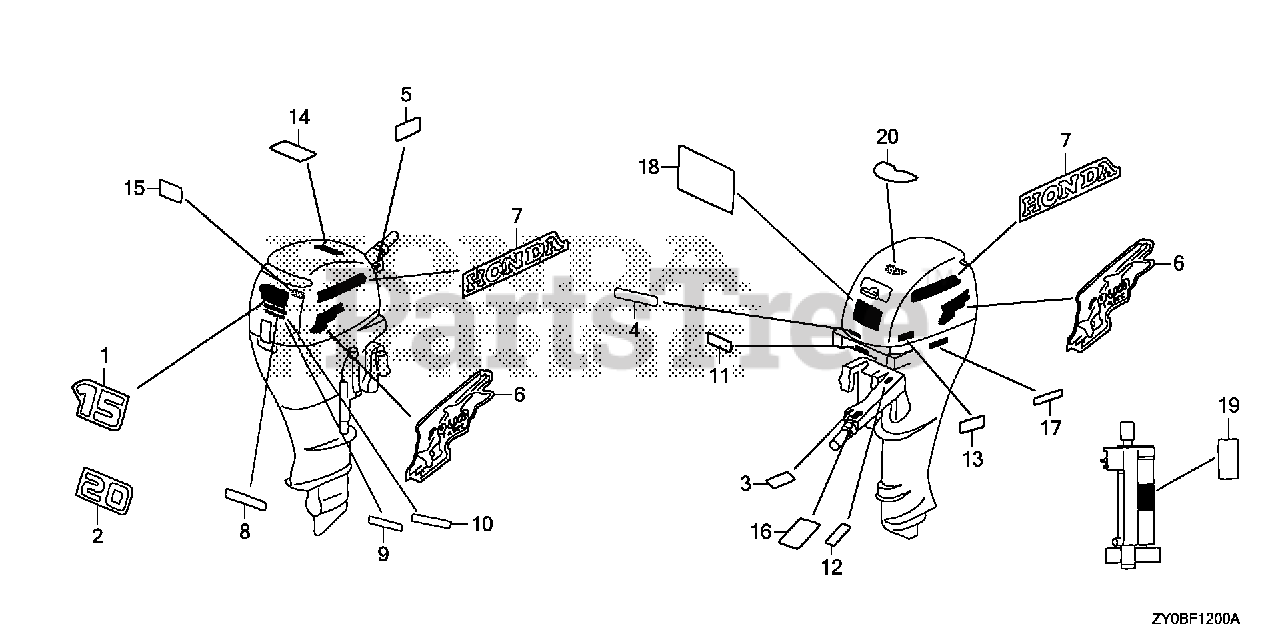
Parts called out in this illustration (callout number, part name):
1	MARK, RR. (15)
4	MARK, SPARE CLIP (ENGLISH)
6	MARK, SIDE
7	MARK, SIDE STRIPE (HONDA)
8	MARK, POWER THRUST
10	MARK, POWER TILT
15	LABEL, OIL CAUTION (ENGLISH)
17	LABEL, STORING CAUTION (ENGLISH)
18	LABEL, WARNING OPERATOR (ENGLISH)
20	MARK, EMERGENCY STARTER (ENGLISH)
